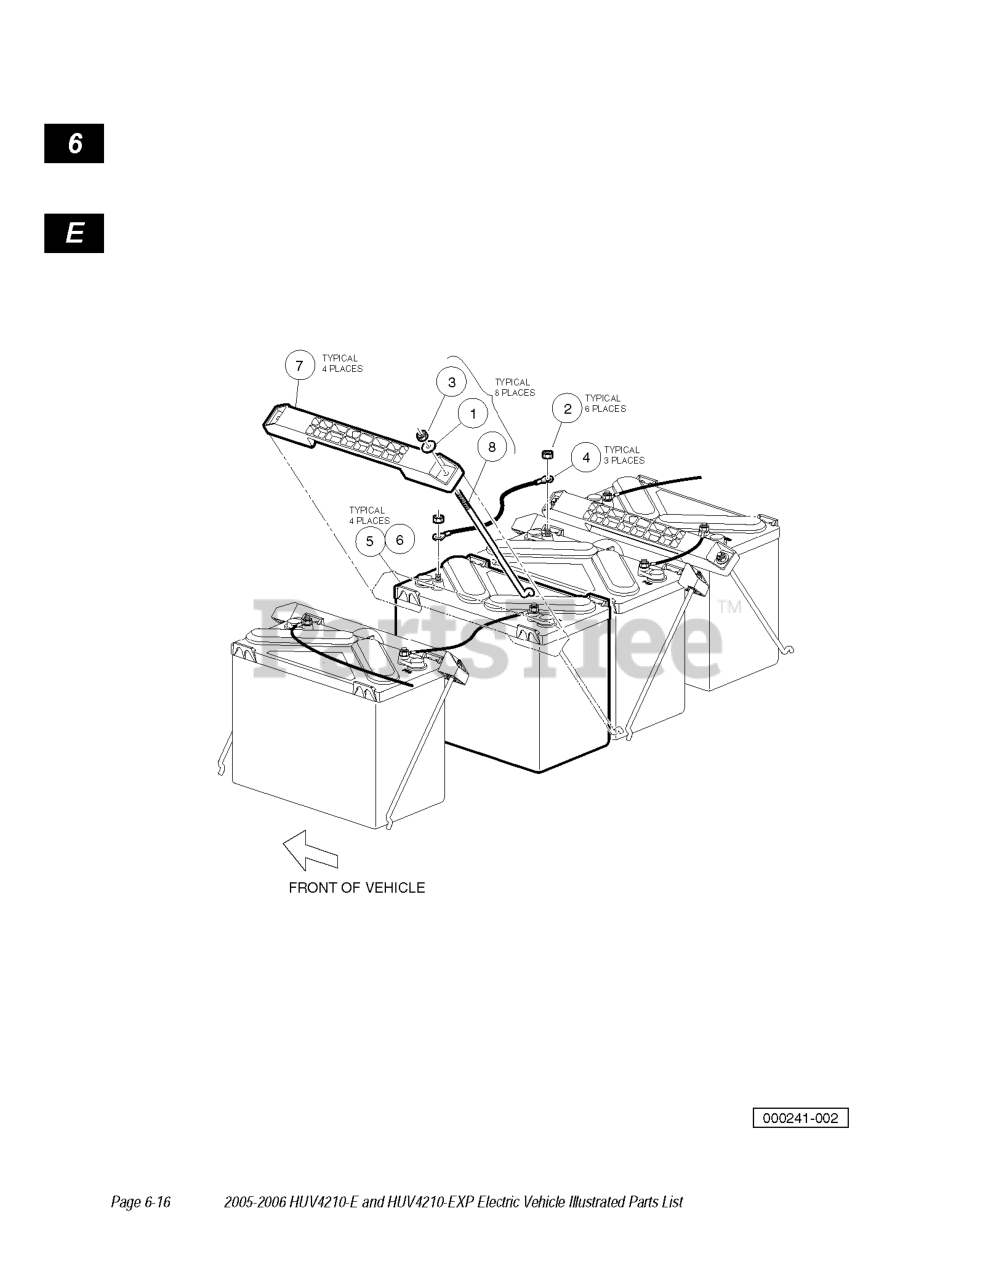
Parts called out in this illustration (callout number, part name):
1	WASHER, 5/16 FLAT
2	NUT, 5/16-18 STAINLESS STL.HEX
3	LOCKNUT, 5/16-18 NYLON INSERT
4	WIRE ASSEMBLY #6 BLACK
5	BATTERY-VENTMASTER 12V(WET)
6	BATTERY 12V TROJAN T1275 DRY
7	12V BATTERY HOLD DOWN
8	BOLT, BATTERY"J"
